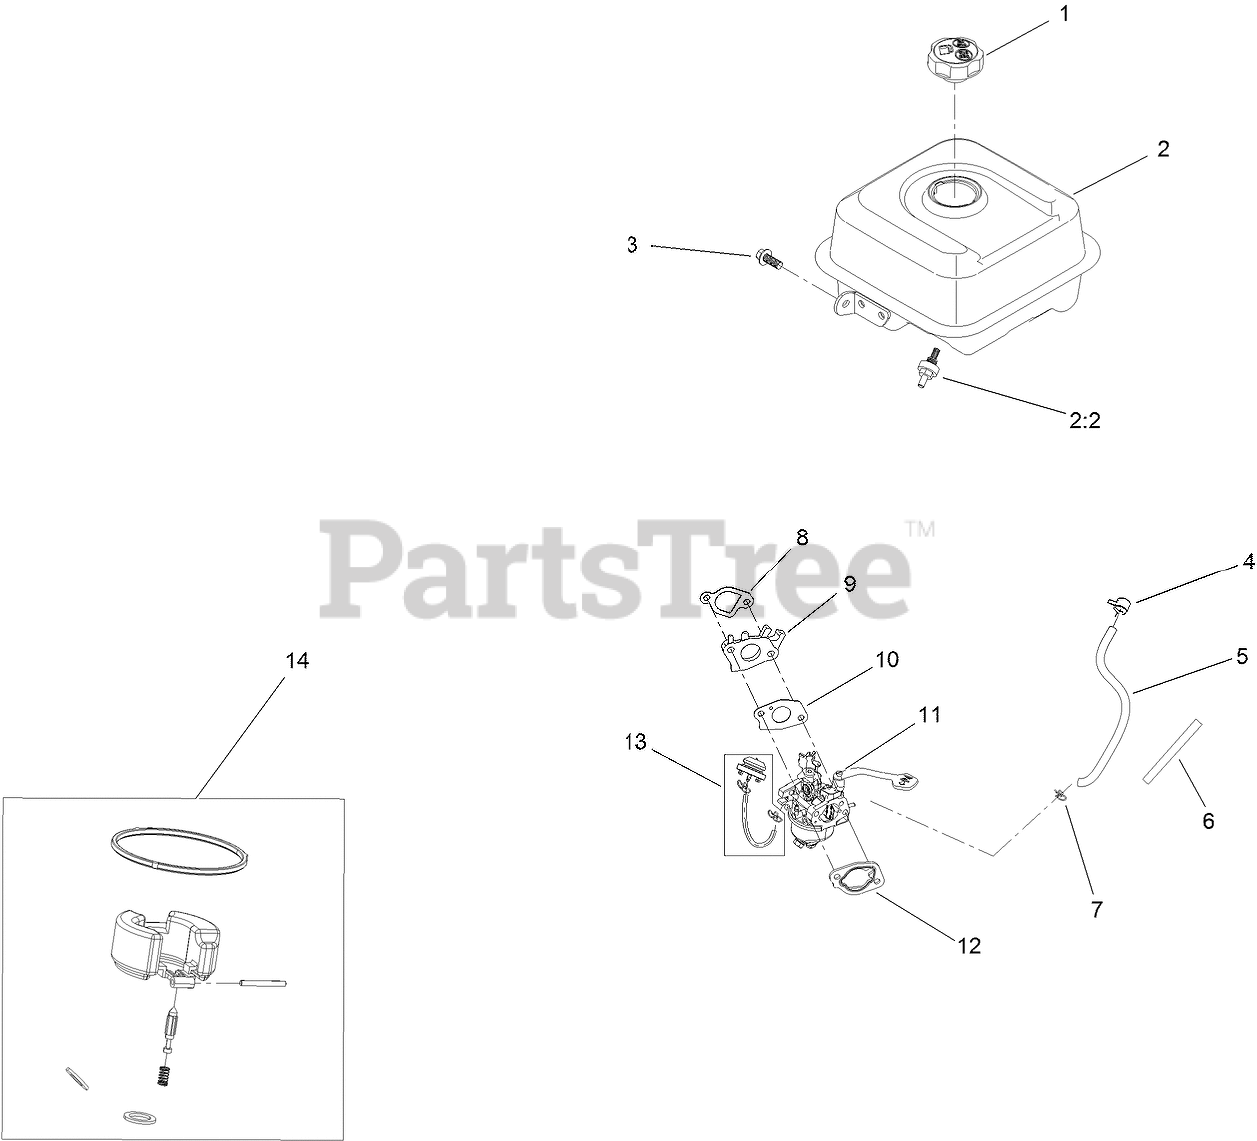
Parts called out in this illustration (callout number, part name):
1	CAP-FUEL
2	FUEL TANK AND FILTER ASM
2:2	FILTER-FUEL
3	SCREW-HHF
4	CLAMP-HOSE
5	HOSE-FUEL
6	SLEEVE-ABRASION
7	CLAMP-HOSE
8	GASKET-CARBURETOR
9	INSULATOR-CARBURETOR
10	GASKET-CARBURETOR
11	CARBURETOR ASM
12	GASKET-CARBURETOR
13	PRIMER KIT
14	INTERNAL CARB SERVICE KIT
